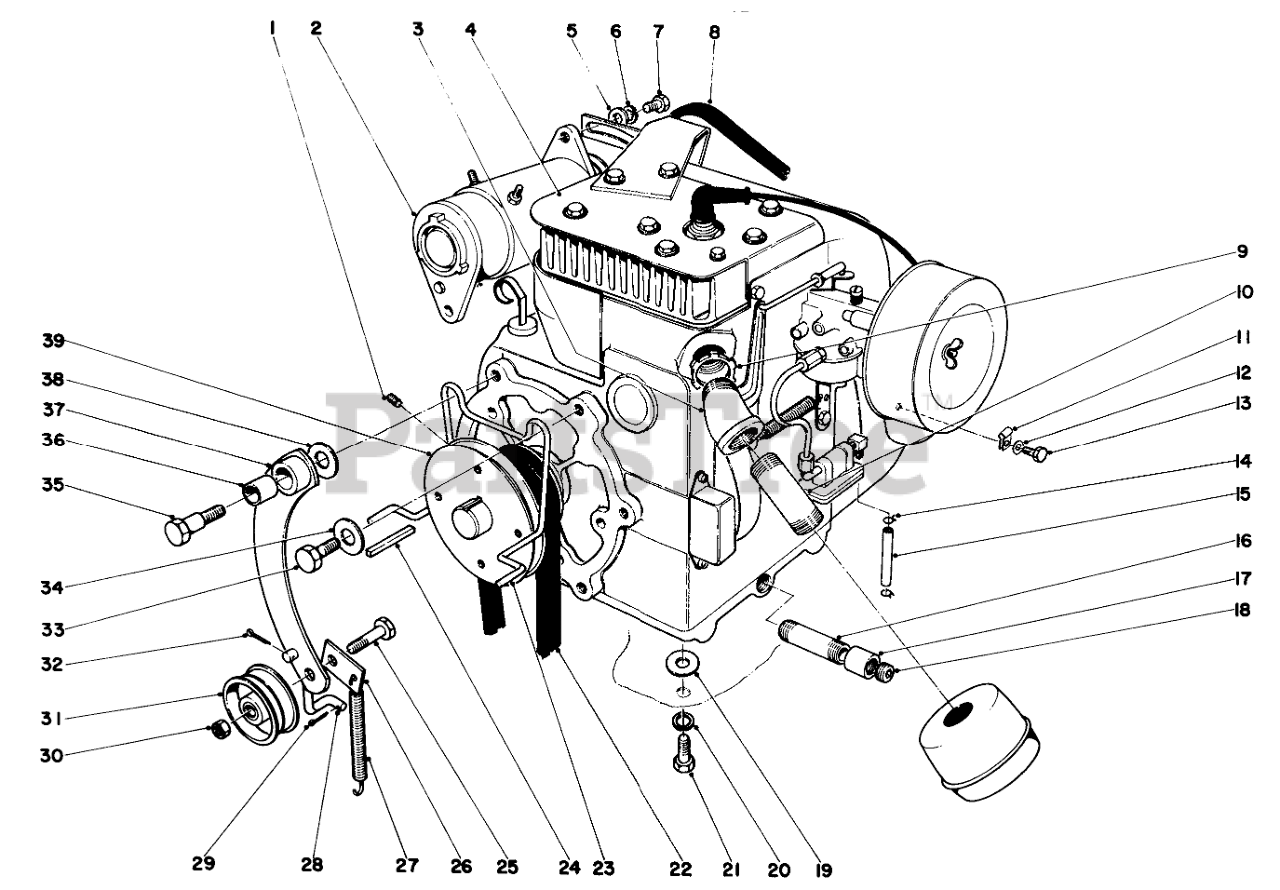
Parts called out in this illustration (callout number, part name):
1	SCREW-SET
2	Generator
3	Street Elbow
4	Engine 950
5	WASHER-FLAT
6	WASHER-LOCK
7	SCREW-HH
8	Belt, Starter Generator
9	Locknut
10	Pipe Nipple
11	Cable Clamp
12	WASHER-FLAT
13	SCREW-HH
14	Hose Clamp
15	Gas Hose
16	Nipple
17	Coupling
18	Pipe Plug
19	WASHER-FLAT
20	WASHER-LOCK
21	SCREW-HH
22	V-BELT MATCHED SET
23	Belt Guide
24	KEY-SQUARE
25	Leveler Head Bolt
26	Spring Tab
27	Spring
28	Idler Rod
29	PIN-COTTER
30	NUT-HEX
31	Idler Pulley
32	PIN-COTTER
33	SCREW-HH
34	WASHER-FLAT
35	Shoulder Bolt
36	Bushing
37	Idler Arm
38	Washer
39	Pulley Engine
